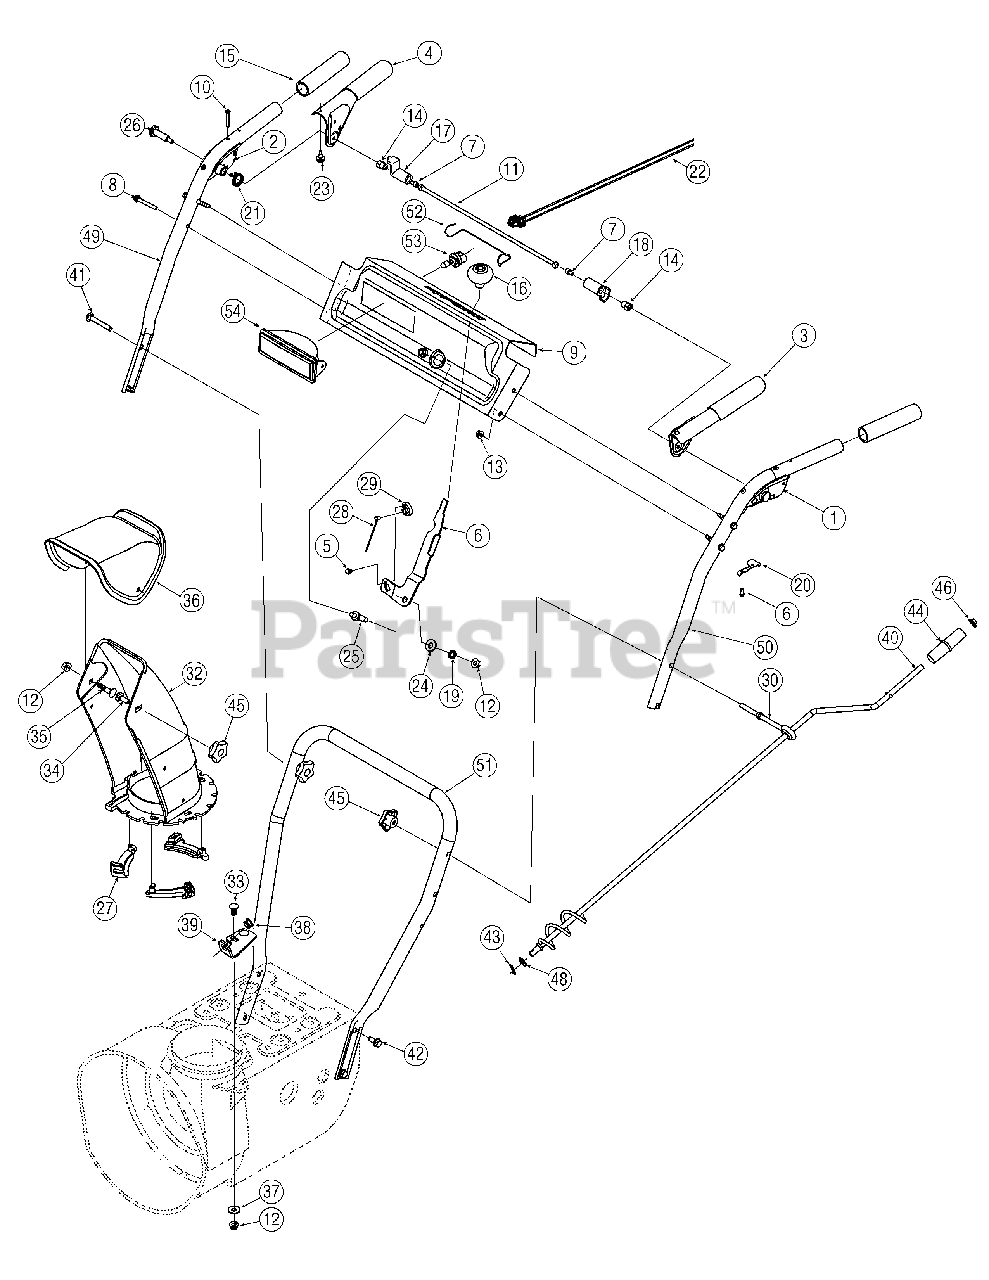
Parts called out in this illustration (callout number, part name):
1	Handle Assembly, Clutch Lock, LH
2	Handle Assembly, Clutch Lock, RH
3	Handle Ass’y, Engage, Black, LH
3	Handle Ass’y, Engage, Yellow, LH
4	Handle Ass’y, Engage, Black, RH
4	Handle Ass’y, Engage, Yellow, RH
5	Screw, #10-16, 0.500
6	Screw, #8-16 x .50
7	Screw, 1/4-20, .375
8	Hex Screw, 1/4-20, 1.50, Gr5
10	Screw, Machine, #10-24, 1.375
11	Pivot Rod
12	Nut, Flange Lock, 5/16-18, Nylon
13	Nut, Flange Lock, 1/4-20, Nylon
14	Nut, Hex, 1/4-20, Shoulder
15	Grip, 1.0 ID x 5.0
16	Knob, Shift, Black
16	Knob, Shift, Yellow
17	Lock Plate
18	Cam, Clutch Lock
19	Spring, .39 x .60 x .88
20	Spring, Clutch Lock
21	Spring, Torsion, 0.8156 ID x .3038
22	Wire Harness, Lamp
23	Bumper, Rubber, .62 OD x .22
24	Washer, Flat, .385 x .870 x .092
25	Bolt, Shoulder, 5/16-18 x 0.905
26	Screw, Shoulder, .43 x 1.3, 1/4-20
27	Chute, Flange Keeper
28	Cable, Speed Selector
29	Houlder, Cable Barrel, LH
30	Eye Bolt, Chute Crank
33	Bolt, Carriage, 5/16-18, 1.0
34	Bolt, Carriage, 5/16-18, 1.0
35	Bolt, Carriage, 5/16-18, .750
36	Chute, Upper, w/ Label
37	Washer, .349 x .879 x .063
38	Bushing, Plastic, .380
41	Screw, Carriage, 5/16-18, 2.25
42	Screw, 5/16-18, 0.75, Gr5
43	Pin, Cotter, .072 x 1.13
44	Crank Knob, 1.0 Dia. x 3.2, Black
45	Knob, 5/16-18, Black
45	Knob, 5/16-18, Yellow
46	Cap, Push, 3/8 Rod
47	Grommet, .44 ID x .94 OD x .50
48	Washer, Flat, .375 x .738 x .063
52	Retainer, Lens
53	Lamp, Halogen, 12V, 27W
54	Lens Assembly, Lamp
